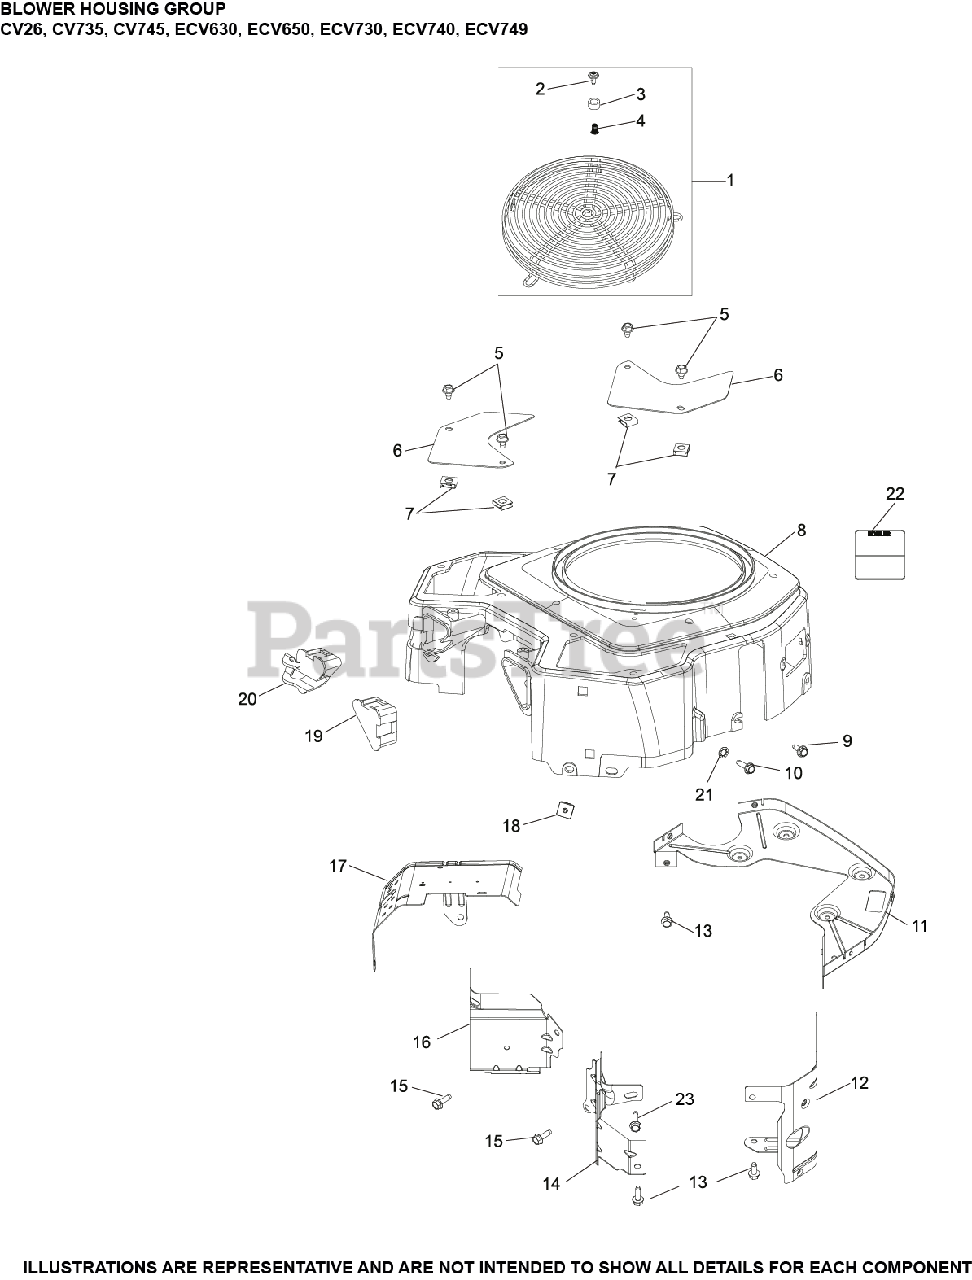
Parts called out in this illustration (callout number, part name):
1	KIT, GUARD
2	SCREW, SEMS
3	SPACER USE 25 112 30-S
4	INSERT, THREADED USE 25 332 19-S
5	SCREW, FLNG THD FRM M6X1.0X10 USE 25 086 406-S
6	KIT, ACCESS PANEL
7	CLIP, BAFFLE MOUNTING USE 25 154 37-S
8	HOUSING, BLOWER
9	SCREW,FLG THD FRM M5X0.8X16-(#25086398S)
10	SCREW,FLG THD FRM M6X1.0X20-(#25086396S)
11	PLATE, BACKING
12	BARREL, LEFT BAFFLE-(#24063112S)
13	SCREW,FLG THD FRM M6X1.0X16-(#25086397S)
14	BAFFLE, VALLEY #2 CYLINDER
15	SCREW, FLG THD FRM M5X.8X10
16	BAFFLE, VALLEY #1 CYLINDER
17	BAFFLE, BARREL
18	NUT, PLASTIC
19	COVER, BLOWER HOUSING USE 24 096 160-S
20	COVER, BLOWER HOUSING-MOLDED USE 24 096 161-S
